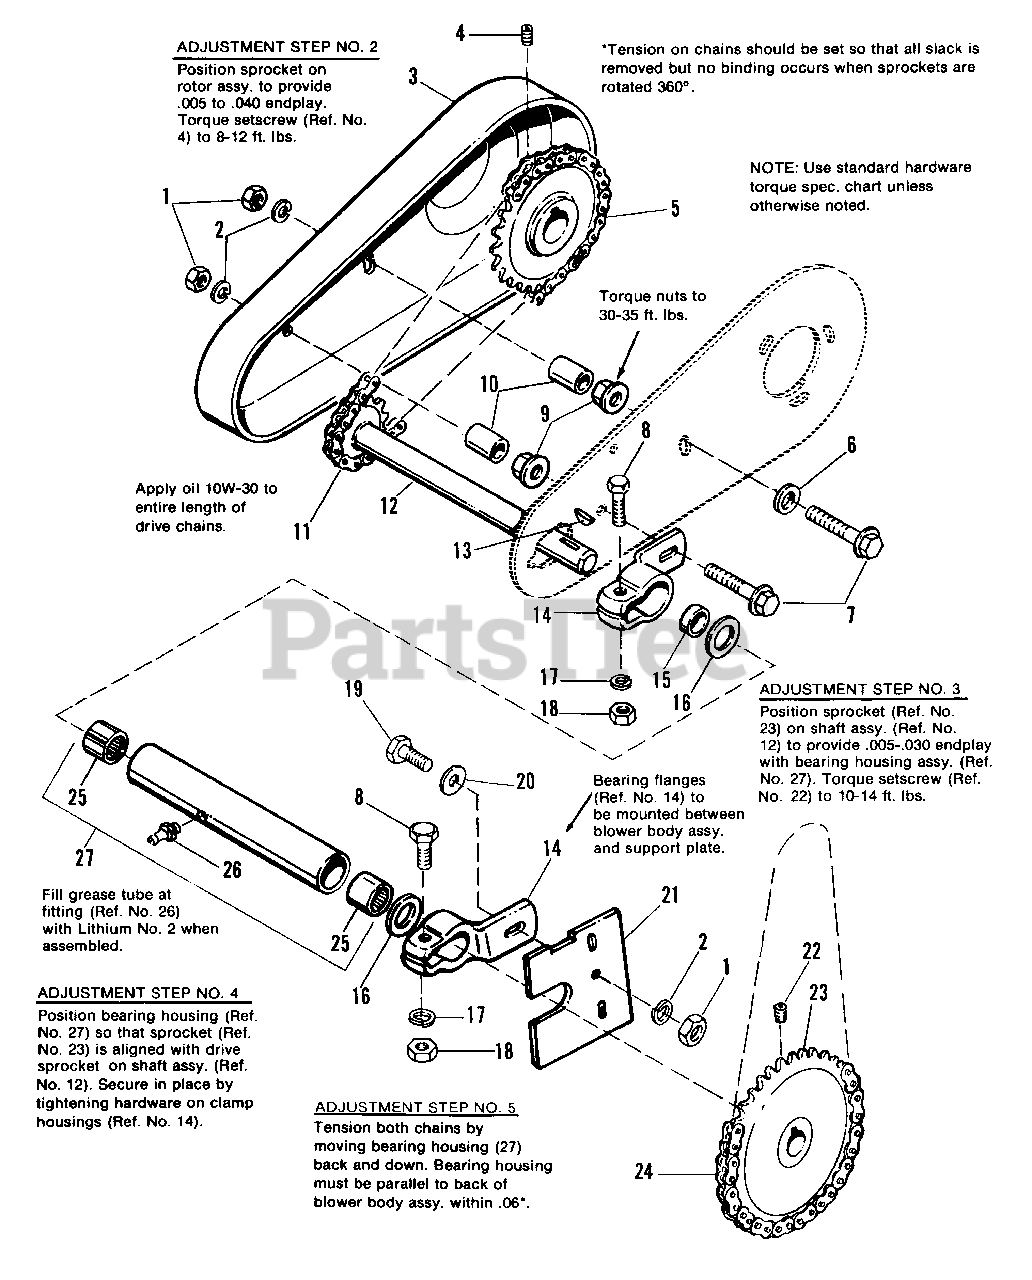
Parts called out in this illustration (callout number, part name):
1	NUT, Hex, Full, 3/8-16
2	LOCKWASHER, 3/8
3	GUARD, Chain
4	SETSCREW, 5/16-18 x 1/2
5	SPROCKET, Rotor
7	SCREW, Cap, Flange, Whiz, 3/8-16 x 2-1/4
8	CAPSCREW, Hex Hd., 5/16-18 x 1-3/4
9	NUT, Flange, Whiz, 3/8-16
11	CHAIN (Auger Drive)
12	SHAFT ASSY. (524 & 724)
12	SHAFT ASSY. (828 & 1028)
13	KEY, Woodruff, #9, 3/16 x 3/4
17	LOCKWASHER, 5/16
18	NUT, Hex, Full, 5/16-18
19	CAPSCREW, Hex Hd., 3/8-16 x 7/8
20	WASHER, Plain, 3/8
21	PLATE, Adjusting
22	SETSCREW, 5/16-18 x 5/16
23	SPROCKET (Cross Shaft)
24	CHAIN (Second Stage to Cross Shaft Assy.)
25	BEARING, Needle
26	FITTING, Grease
27	HOUSING ASSY., Bearing (524 & 724)
27	HOUSING ASSY., Bearing (828 & 1028)
